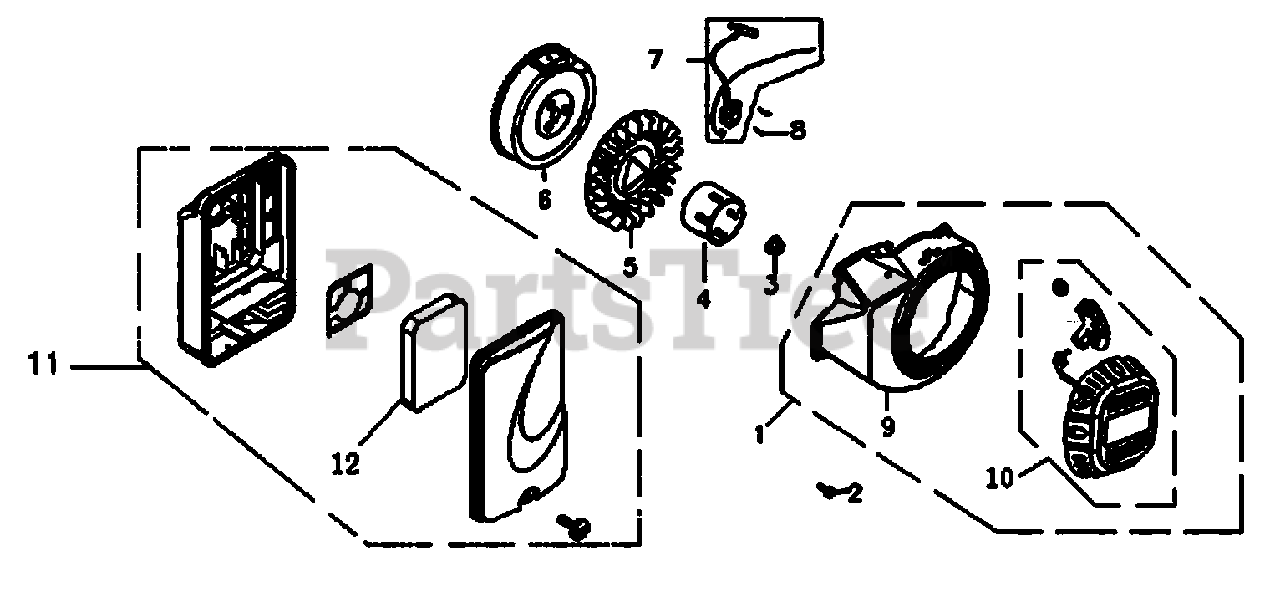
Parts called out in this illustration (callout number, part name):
1	STARTER ASSY., W/HOUSING
2	BOLT, FLANGE
3	NUT SPECIAL, M16
4	PULLEY, STARTER
5	FAN, COOLING
7	COIL ASSY, IGNITION
8	BOLT, FLANGE
9	HOUSING, BLOWER
10	RECOIL COVER ASSY - LEFT PULL
11	CLEANER ASSY, AIR
12	ELEMENT, AIR CLEANER
